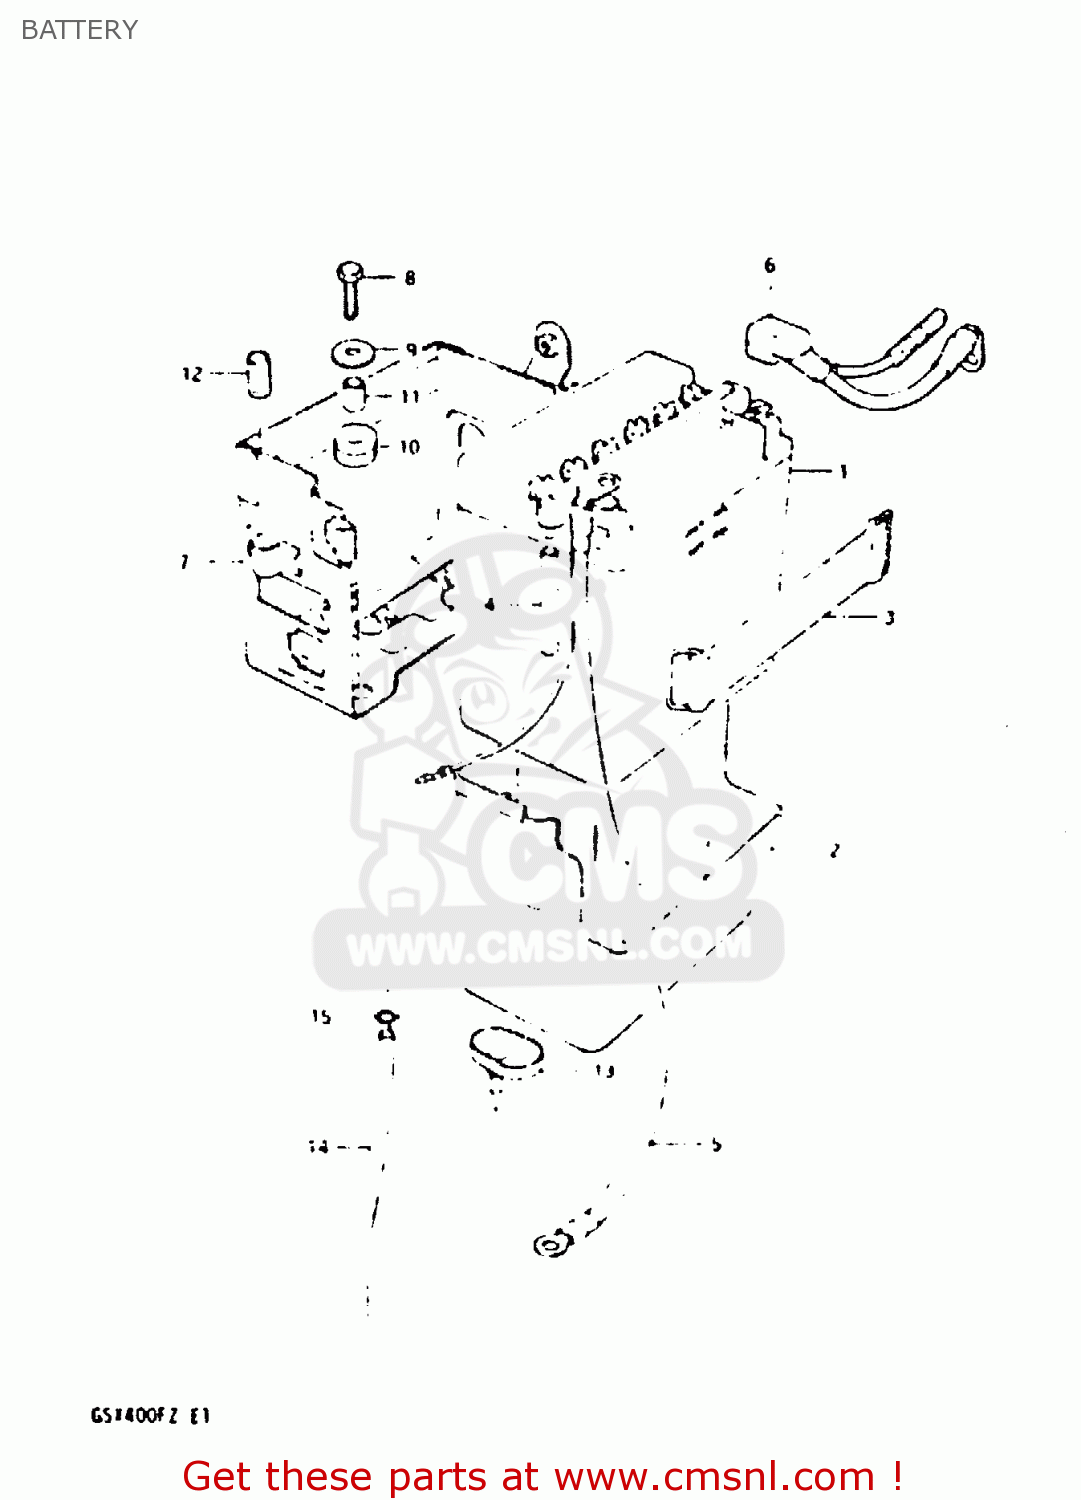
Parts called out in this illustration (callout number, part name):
1	BATTERY ASSY (12V)
2	CASE,BATTERY
3	BAND
4	HOSE, EXHAUST (L:45)
5	LEAD WIRE, (-)
6	LEAD WIRE, (+)
7	HOLDER, BATTERY
8	BOLT L:16
9	WASHER
10	CUSHION
11	SPACER(6.1X9X7.5)
12	CUSHION
13	FUNNEL,BATTERY EXHAUST
14	HOSE,BATTERY EXHAUST
15	CLIP
